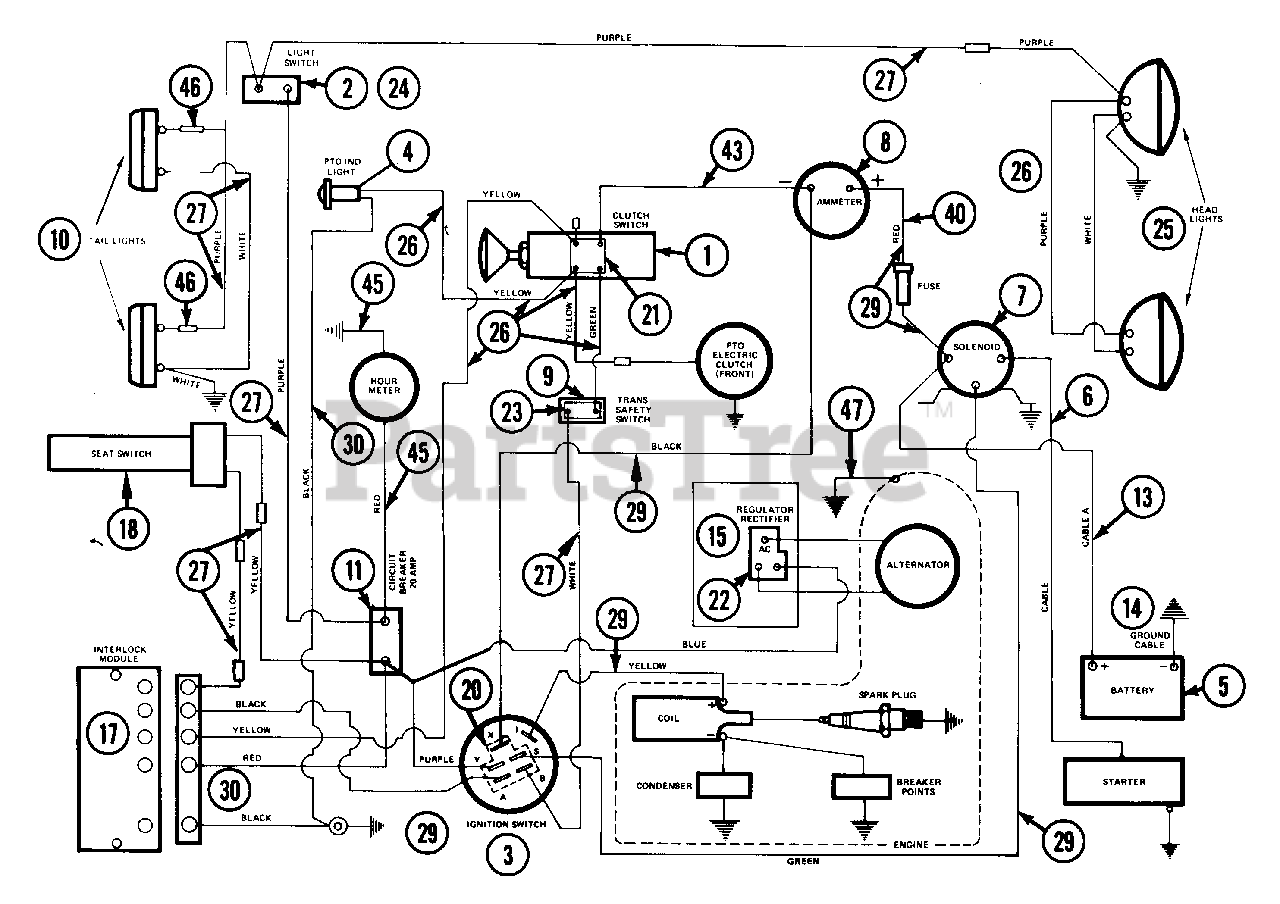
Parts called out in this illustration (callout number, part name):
1	CLUTCH SWITCH
2	LIGHT SWITCH
3	SWITCH & KEY SET ASSEMBLY
4	PTO INDICATOR LIGHT
4	LAMP SOCKET
4	SPEED NUT
5	BATTERY
6	GROUND CABLE .31X22.00X.31
7	SOLENOID
8	AMMETER
9	SAFETY SWITCH
10	TAIL LIGHT
11	CIRCUIT BREAKER
14	GROUND CABLE
15	REGULATOR RECTIFIER
17	INTERLOCK MODULE
18	SWITCH SEAT
20	CONNECTOR HOUSING
21	CONNECTOR
22	CONNECTOR
23	CONNECTOR
24	CONNECTOR
25	HEAD LIGHT
26	HEADLIGHT & CLUTCH HARNESS
27	TAIL LIGHT HARNESS ASSEMBLY
29	DASH HARNESS
30	INTERLOCK MODULE HARNESS
40	STD 30 AMP FUSE
43	INTERLOCK WIRE
45	WIRING HARNESS
46	MALE DISCONNECT ADAPTER
47	GROUND CABLE .31X22.00X.31
47	WSHR-LK .312X.097 PL HVY
47	NUT-JAM .312-24 PL
47	WSHR-LK 10X.047 MED PL
47	NUT 10-32 PL
